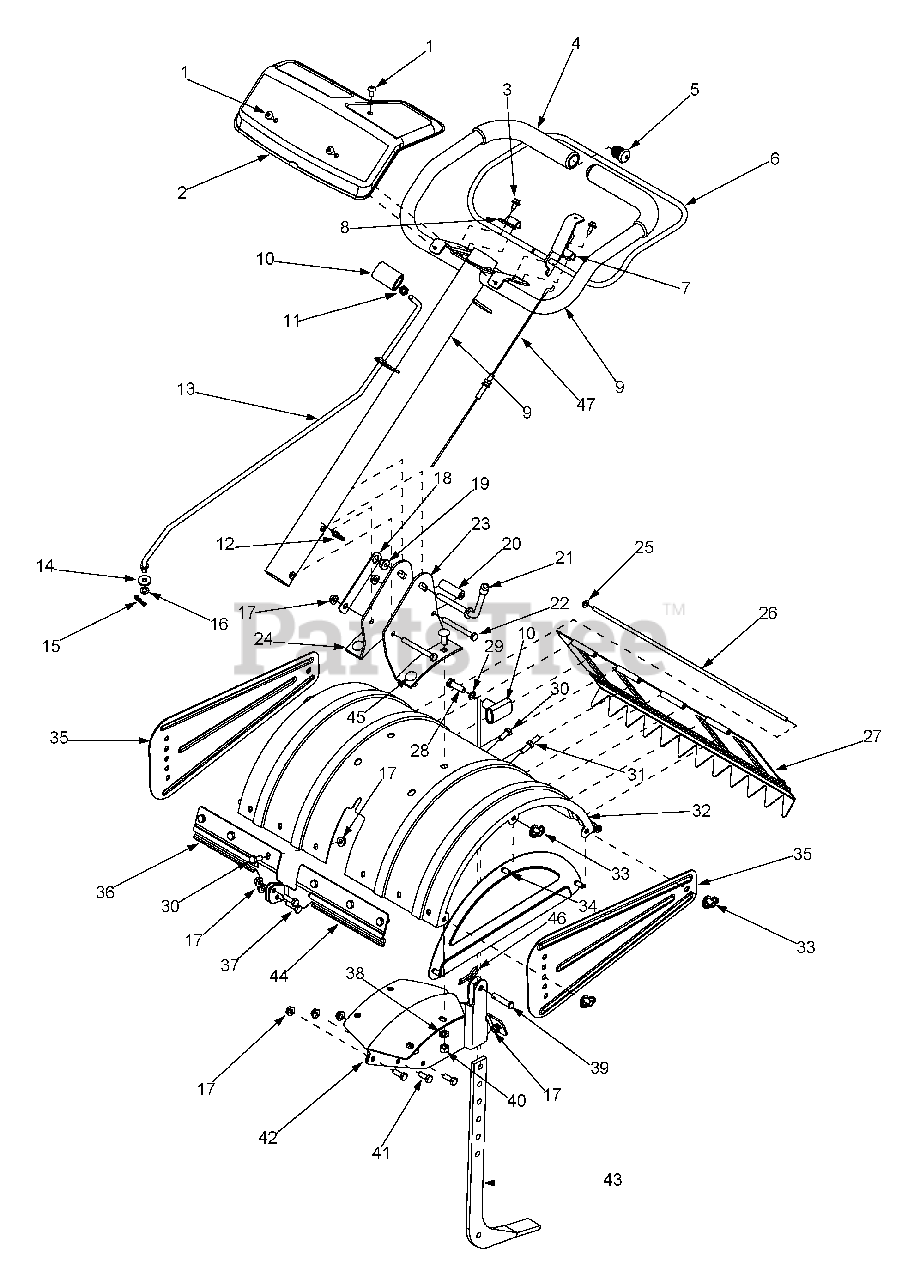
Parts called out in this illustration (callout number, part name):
1	Tap Screw 1/4-14 x.625
4	Foam Grip
5	End Plug
11	Jam Nut 3/8-16
12	Cable Clip
13	Shift Control
14	Rubber Washer.33 ID x.87 OD
15	Cotter Pin
16	Flat Washer.344 ID x.62 OD
17	Hex Flange Lock Nut 5/16-18
18	Retainer Bracket
19	Flange Lock Nut 3/8-24
20	Spacer.322 ID x.625 OD
21	Handle Adjustment Crank
22	Hex Screw 5/16-18 x 3.0
28	Hex Cap Screw 3/8-16 x 1.25
29	Flat Washer.375 ID x.620 OD
30	Hex Cap Screw 5/16-18 x.75
31	Hex Screw 5/16-18 x.75
37	Hex Cap Screw 5/16-18 x 1.0
38	Lock Washer 3/8
39	Clevis Pin
40	Hex Nut 3/8-16
41	Hex Cap Screw 5/16-18 x.875
45	Carriage Bolt 3/8-16 x 1.0
46	Cotter Pin
47	Clutch Cable
